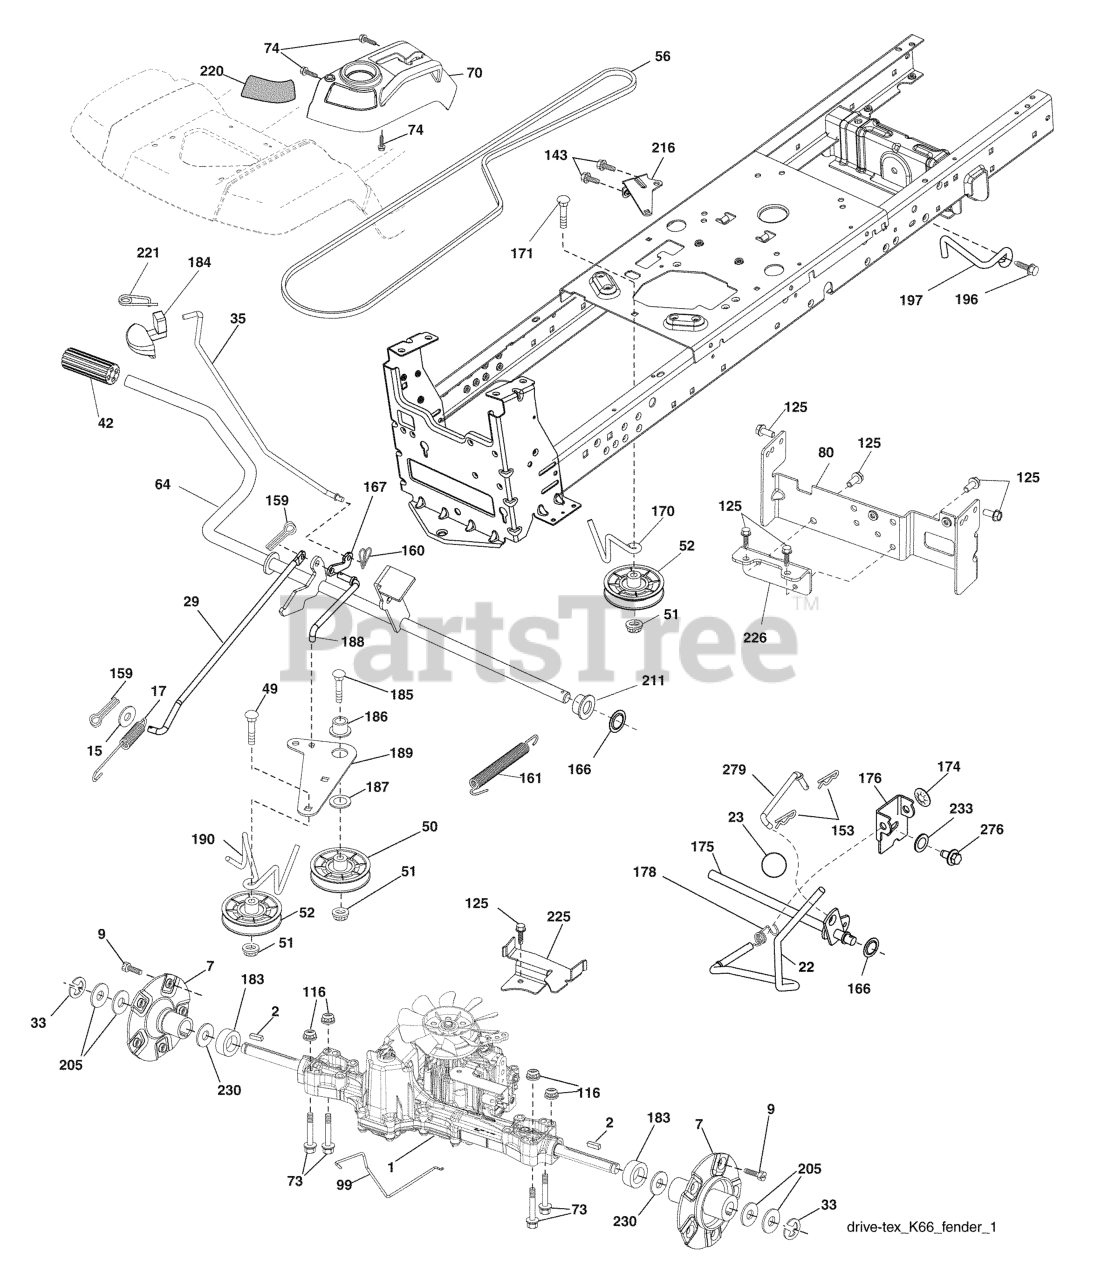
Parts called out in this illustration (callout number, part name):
1	TRANSAXLE.K66.AD.FCH.TG
2	KEY 1/4 X 2.5
7	HUB.ASM.WHEEL.REAR.23"TEX
9	HUB BOLT
15	WASHER
17	SPRING.BRAKE.K46
22	ROD.SHIFT.FENDER.STGT.
23	KNOB.DELUXE.(PISTOL.GRIP).BLAC
29	ROD.BRAKE.K66
33	E RING HYT
35	ROD.BRAKE.PARKING.GT.H
42	PEDAL COVER T
50	IDLER.FLAT.910.OFFSET
51	NUT LOCK FLG 3/8-16 UNC
52	IDLER.V-GROOVE.910.OFFSET
64	SHAFT.ASM.PEDAL.BRAKE.
70	RP CONSOLE.ASM.HYDO.HUSQ.
73	BOLT HEX 5/16-18 GR 5
74	SCREW.HI-LO.CONSOLE
80	STRAP.TORQUE.K66
99	ROD.SPRING.BYPASS.K66.GT.Z
116	NUT LOCK HEX FLANGE 5/16-18
125	SCREW
143	Screw 5/16-18 x 1/2
153	RETAINER M
159	COTTER PIN
160	RETAINER CLIP
161	SPRING, RETURN LT
166	NUT.PUSH.625.2006
167	LATCH.BRAKE.SPRING
170	KEEPER.V-IDLER.CENTER.
171	BOLT
174	NUT.PUSH.500.2006
175	SHAFT.ASM.SHFT.T2.TLT
176	ARM.CLEVIS.ROD.SHIFT
178	SPRING.SHIFT.GT2006
183	SPACER.AXLE.HG.TEX
184	HANDLE.PARKG.BRK.HUSQ X667
185	BOLT
186	SPACER.RETAINER
187	WASHER 12/32X2X10GA
188	RP.LINK.CLUTCH.GROUND.DRIVE
189	BELLCRANK.GROUND.DRIVE.TEX.
190	KEEPER.BELLCRANK.DRIVE
196	SCREW 3/8-16X1
197	BRKT.ANIT-ROTATION.CLUTCH
211	BUSHING.SHAFT.BRAKE.HAND
216	BRACKET.PULLEY.IDLER.W/TEX
220	REFLECTOR.RH.TEX GT
221	RETAINER.SPRING.CLIP.H
225	KEEPER.BELT.TRANSAXLE.K66
226	BRACKET.MOUNT.TORQUE.K66.TG
233	WASHER SERRATED
276	BOLT FIN HEX 7/16-14 X 1
279	LINK.ASM.SHIFT.FENDER.K66
